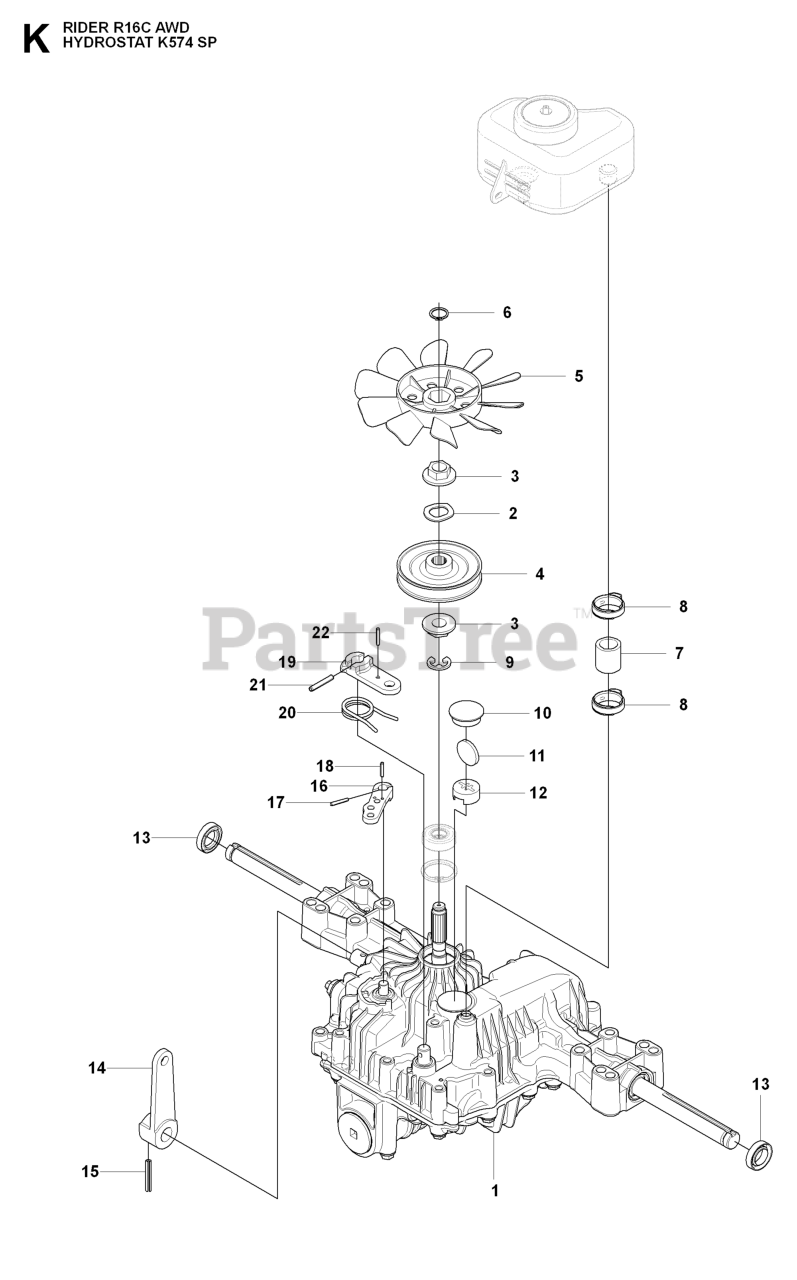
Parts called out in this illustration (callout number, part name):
1	HYDRAULMOTOR
5	FAN.BLACK.1A646083070
6	RETAINING RING **
8	CLAMP
13	RP SEAL.19, 19216334280
14	CONTROL LEVER
20	RETURN SPRING
